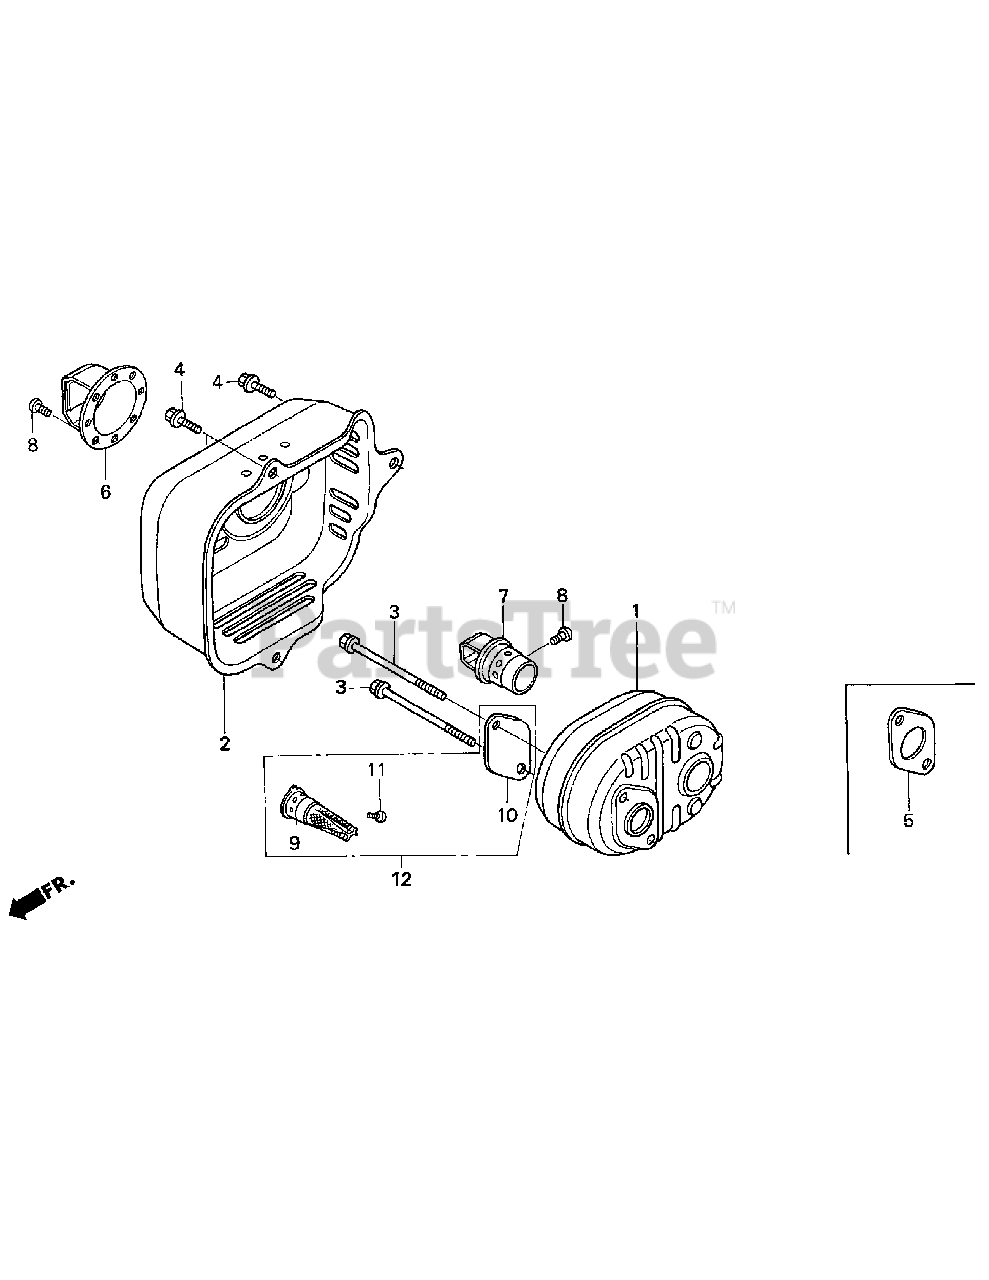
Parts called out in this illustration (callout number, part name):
1	MUFFLER
2	PROTECTOR, MUFFLER
3	BOLT, FLANGE (6X79) (CT200)
4	BOLT, FLANGE (6X12) (CT200)
5	GASKET, MUFFLER
9	ARRESTER, SPARK
10	PLATE, ARRESTER NUMBER
11	SCREW, TAPPING (4X6)
12	ARRESTER KIT, SPARK
